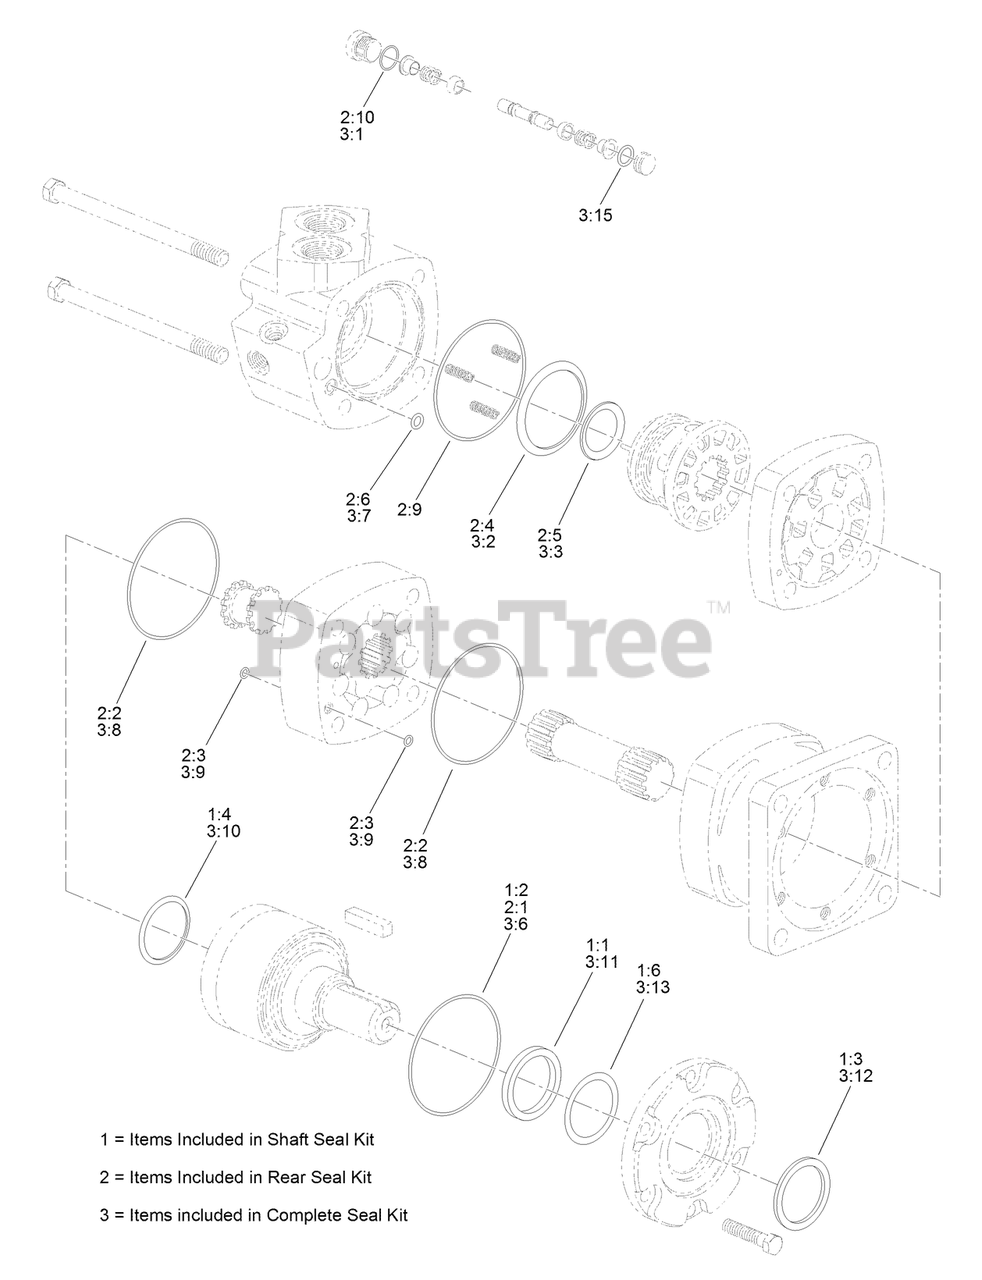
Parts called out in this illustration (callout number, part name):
1	SEAL KIT
1:1	SEAL
1:2	O-RING
1:3	SEAL-DUST
1:4	Seal-Face, Shaft
1:6	RING-BACKUP
2	SEAL KIT
2:1	O-RING
2:2	O-RING
2:3	O-RING
2:4	Seal-Face, Outer
2:5	Seal-Face, Inner
2:6	O-RING
2:9	SEAL
2:10	O-RING
3	SEAL KIT
3:1	O-RING
3:2	Seal-Face, Outer
3:3	Seal-Face, Inner
3:6	O-RING
3:7	O-RING
3:8	O-RING
3:9	O-RING
3:10	Seal-Shaft Face
3:11	SEAL
3:12	SEAL-DUST
3:13	RING-BACKUP
3:15	O-RING
